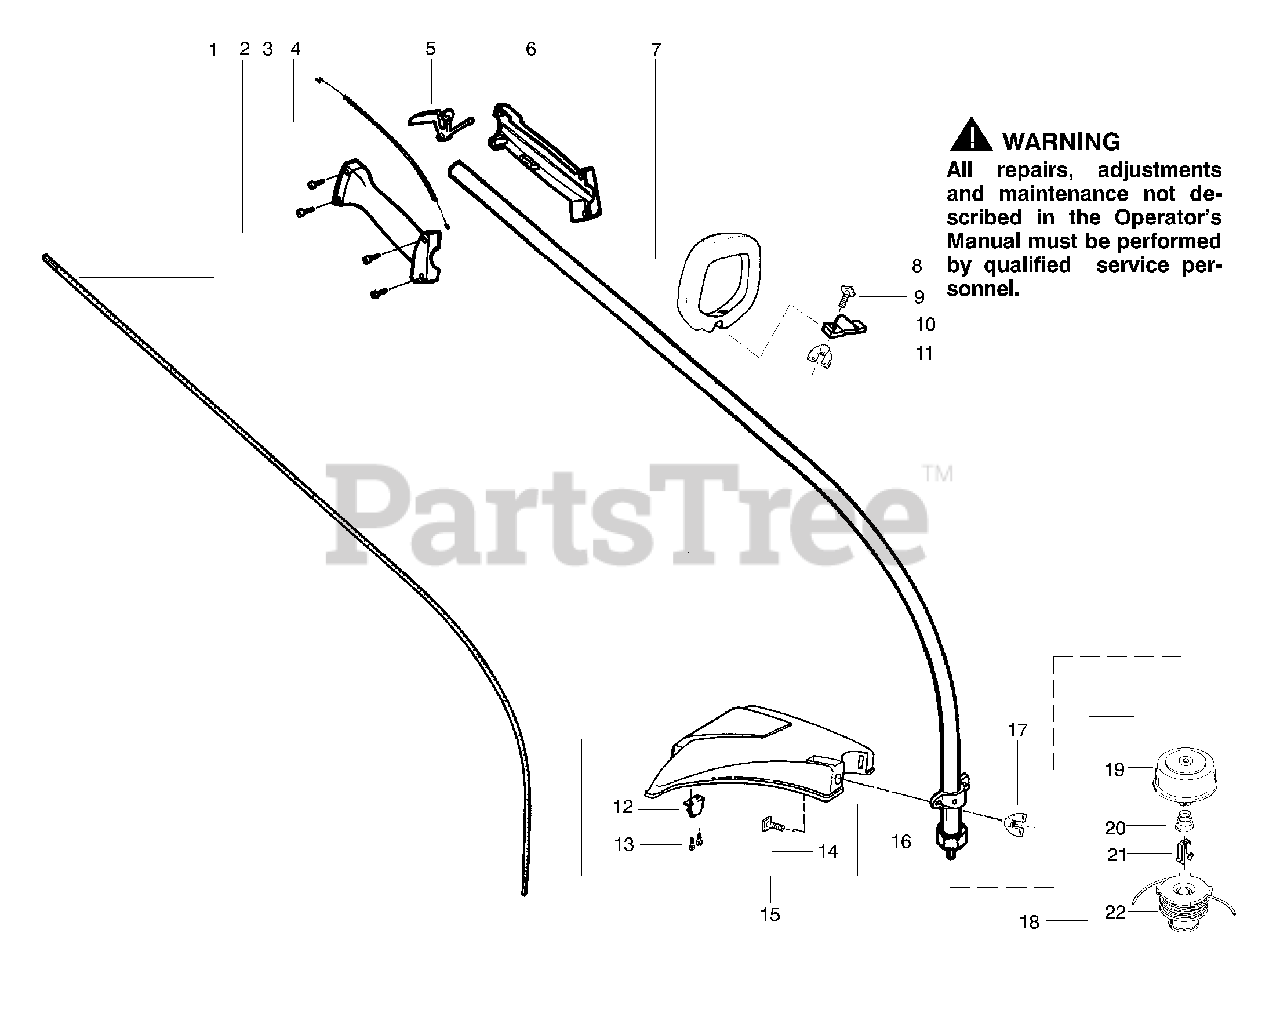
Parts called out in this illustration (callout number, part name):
1	Shaft-Flex
2	Throttle Hsg. (Right)
3	Screw-Throttle Hsg.
4	Assy-Throttle Cable
6	Throttle Hsg. (Left)
7	Assy-Drive Shaft Hsg.
8	Handle-Assist
9	Bolt-Handle/Shield
10	Clamp-Handle
11	Wingnut-Handle/Shield
12	Line Limiter
13	Screw-Line Limiter
14	Bolt-Handle/Shield
15	Kit-Shield Assy
16	Dust Cup
17	Wingnut-Handle/Shield
18	Accy-TNG VI Cutting Head
19	Assy-Hub
20	Spring-Compression
21	Clip-Retainer- Head
22	Accy-Spool w/Line
